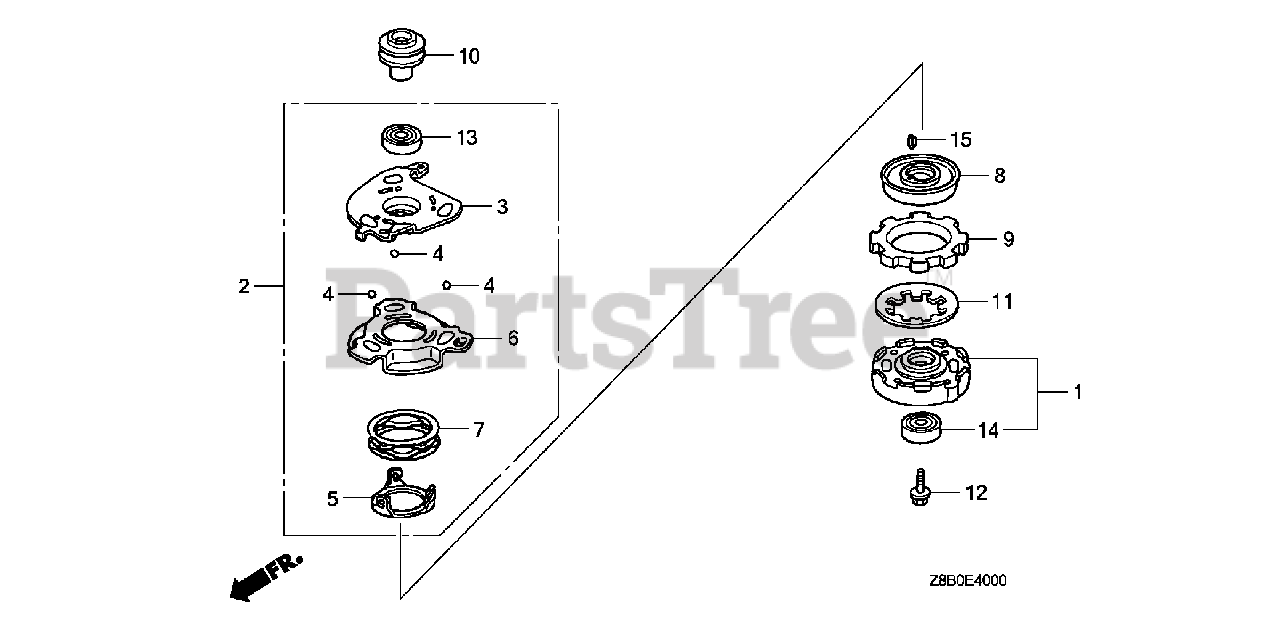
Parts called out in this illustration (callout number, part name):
1	HOLDER ASSY., BLADE
2	PLATE ASSY., BALL CONTROL
3	PLATE, BALL CONTROL
4	BALL, STEEL
5	PLATE, SPRING HOOK
6	PLATE, BRAKE
7	SPRING, BALL PLATE
8	DISK, DRIVE
9	DISK, DRIVEN
10	PULLEY, DRIVE
11	SPRING, CLUTCH
12	BOLT, FLANGE (10X24)
13	BEARING, RADIAL BALL (6006) (SST)
14	BEARING, RADIAL BALL (6204)
15	KEY, WOODRUFF (16X15)
